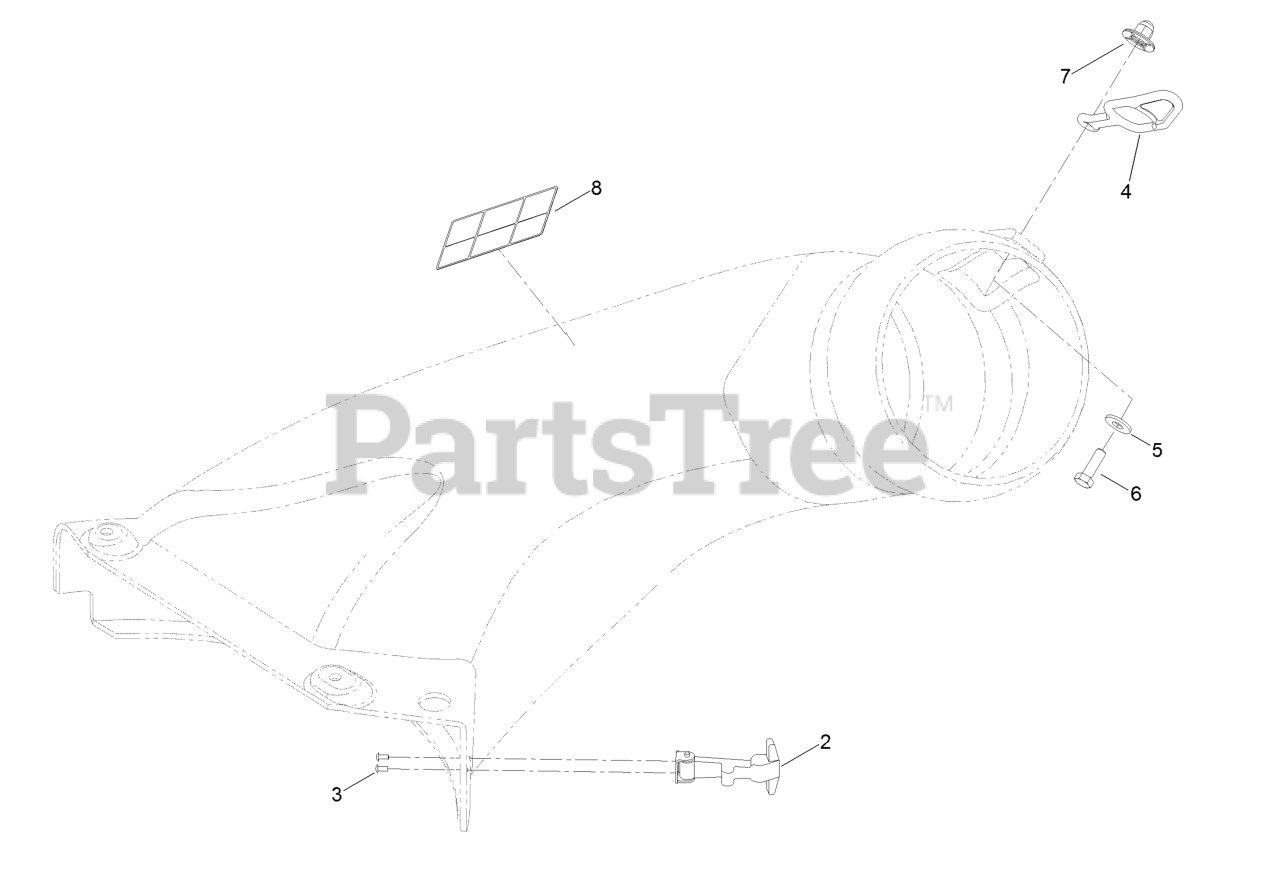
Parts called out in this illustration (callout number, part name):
2	HANDLE ASM
3	RIVET-POP
4	RETAINER-DUCT
5	WASHER-FLAT
6	SCREW-HH
7	NUT-IMPELLER
8	DECAL-DANGER
